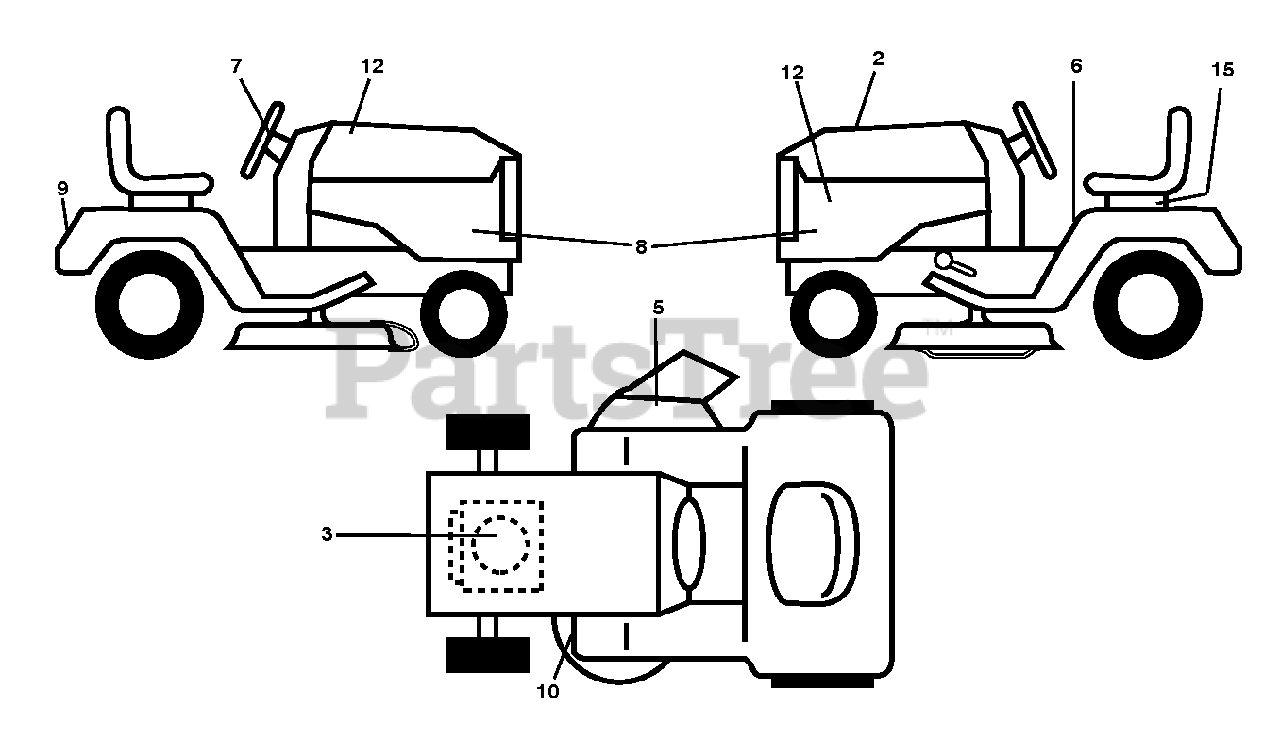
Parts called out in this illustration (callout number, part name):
2	Decal, Replacement BSM31 PB TLW 3
3	DECAL.ENG.BS.15_5PB.DOM.381667
5	DECAL, DECK DEFLECTOR, WARNING
6	DECAL.FENDER.WARNING.ENGLISH
7	Decal, Steering Wheel STDXXSQ PPRO 2015
8	DECAL.SDPNL.PB145G42.BLK.PPRO
9	DECAL.REARFNDR.POULAN PRO.2015
10	DECAL.V-BELT.SCH.42/46"MEC/ELE
12	DECAL.POULAN PRO.2015
15	DECAL BTRY SYMBOLS
